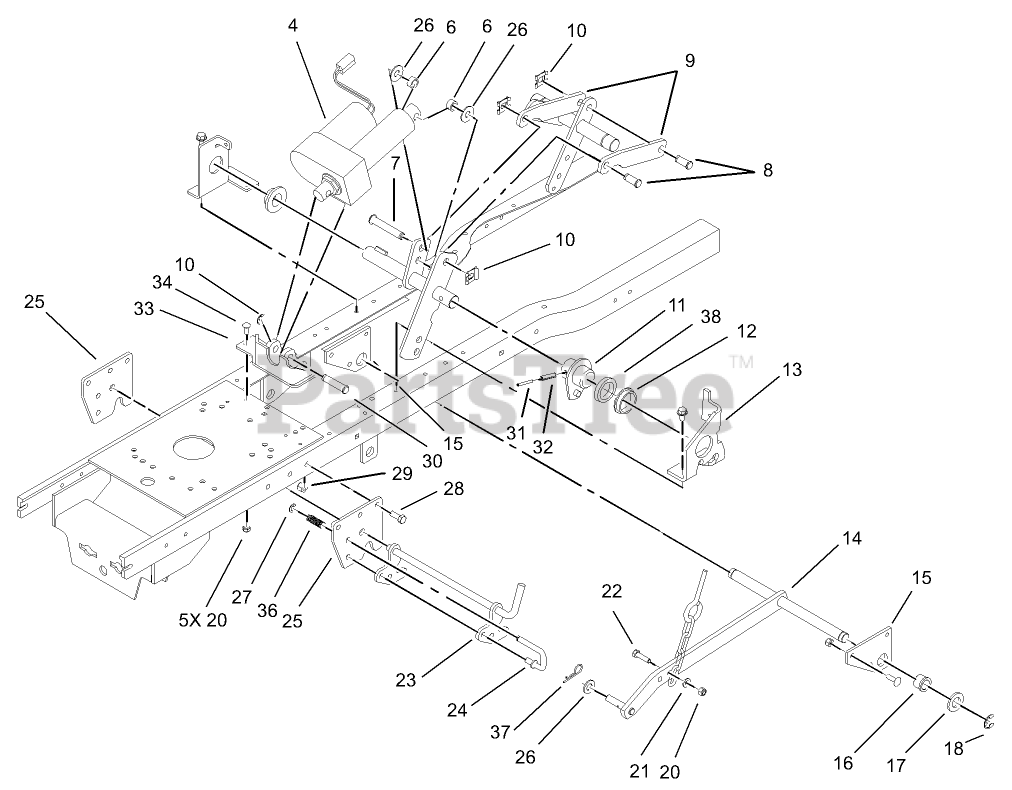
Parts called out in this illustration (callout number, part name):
4	ACTUATOR
6	SPACER
7	PIN-CLEVIS
8	PIN-CLEVIS
9	STRAP-LINK, LIFT
10	CLIP-PIN
12	BUSHING
13	BRACKET-ARM, LIFT
14	LIFT BAR ASM
15	PLATE-LIFT, REAR
16	BUSHING-FLANGE
17	WASHER-FLAT
18	E-RING
20	NUT-LOCK, NI
21	WASHER-PLAIN
22	SCREW-HH
23	MIDHITCH LATCH ASM
24	ROD-CATCH, MIDHITCH
25	PLATE-HITCH
26	WASHER-FLAT
27	RING-RETAINING
28	SCREW-HH
29	NUT-LOCK, NI
30	PIN-CLEVIS
31	PIN-SPRING
32	PIN-ROLL
33	ACTUATOR BRACKET ASM
34	SCREW-CARR
36	SPRING
37	PIN-HAIR
38	SPACER
